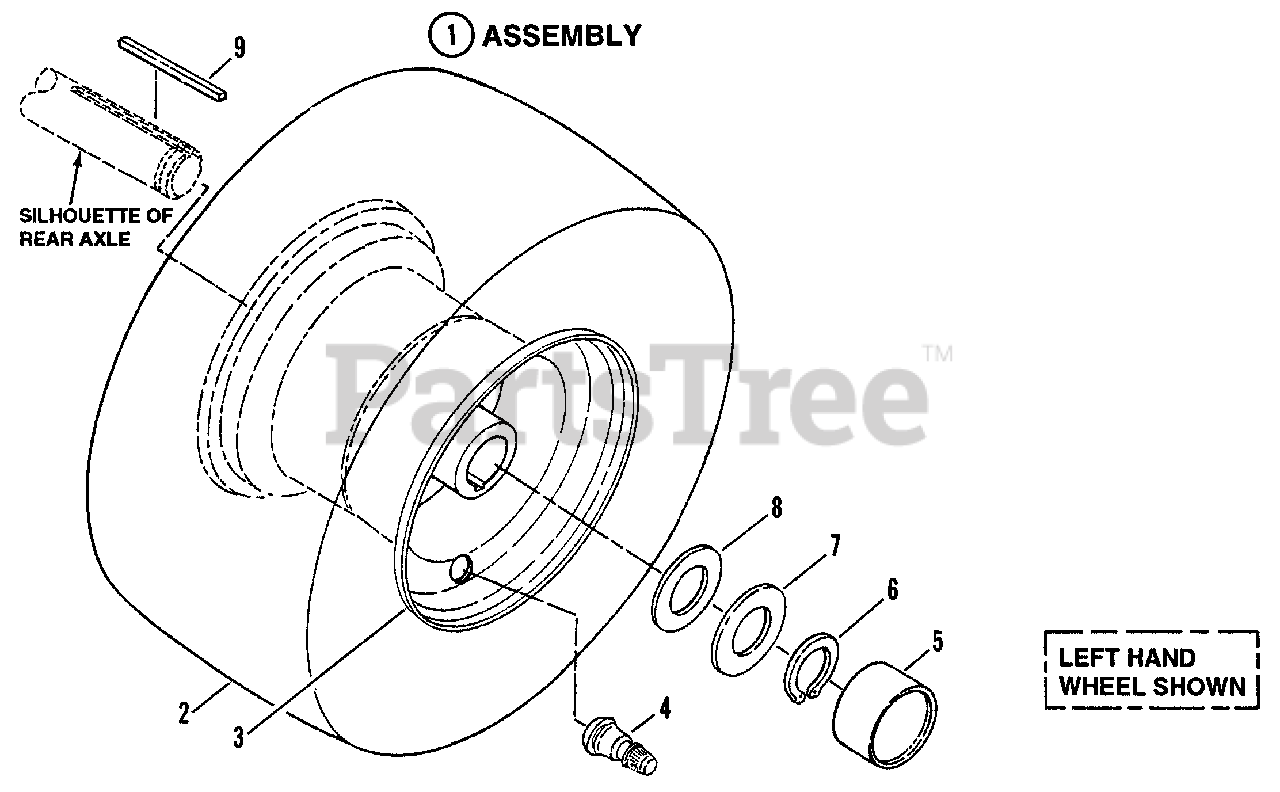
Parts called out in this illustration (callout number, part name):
1	ASSEMBLY, Rear Tire & Rim
2	TIRE, 20 x 10
2	TIRE, 18 x 8.50
3	RIM, 8.00 x 7.00
4	VALVE, Air (Snap-in)
5	HUB-CAP
6	RING, Retaining
7	WASHER, Thrust, 49/64" I.D. x 1 5/8" O.D.
8	WASHER, Flat, 49/64" I.D. x 1 1/2" O.D.
9	KEY, Square, 3/16" x 2 1/2"
